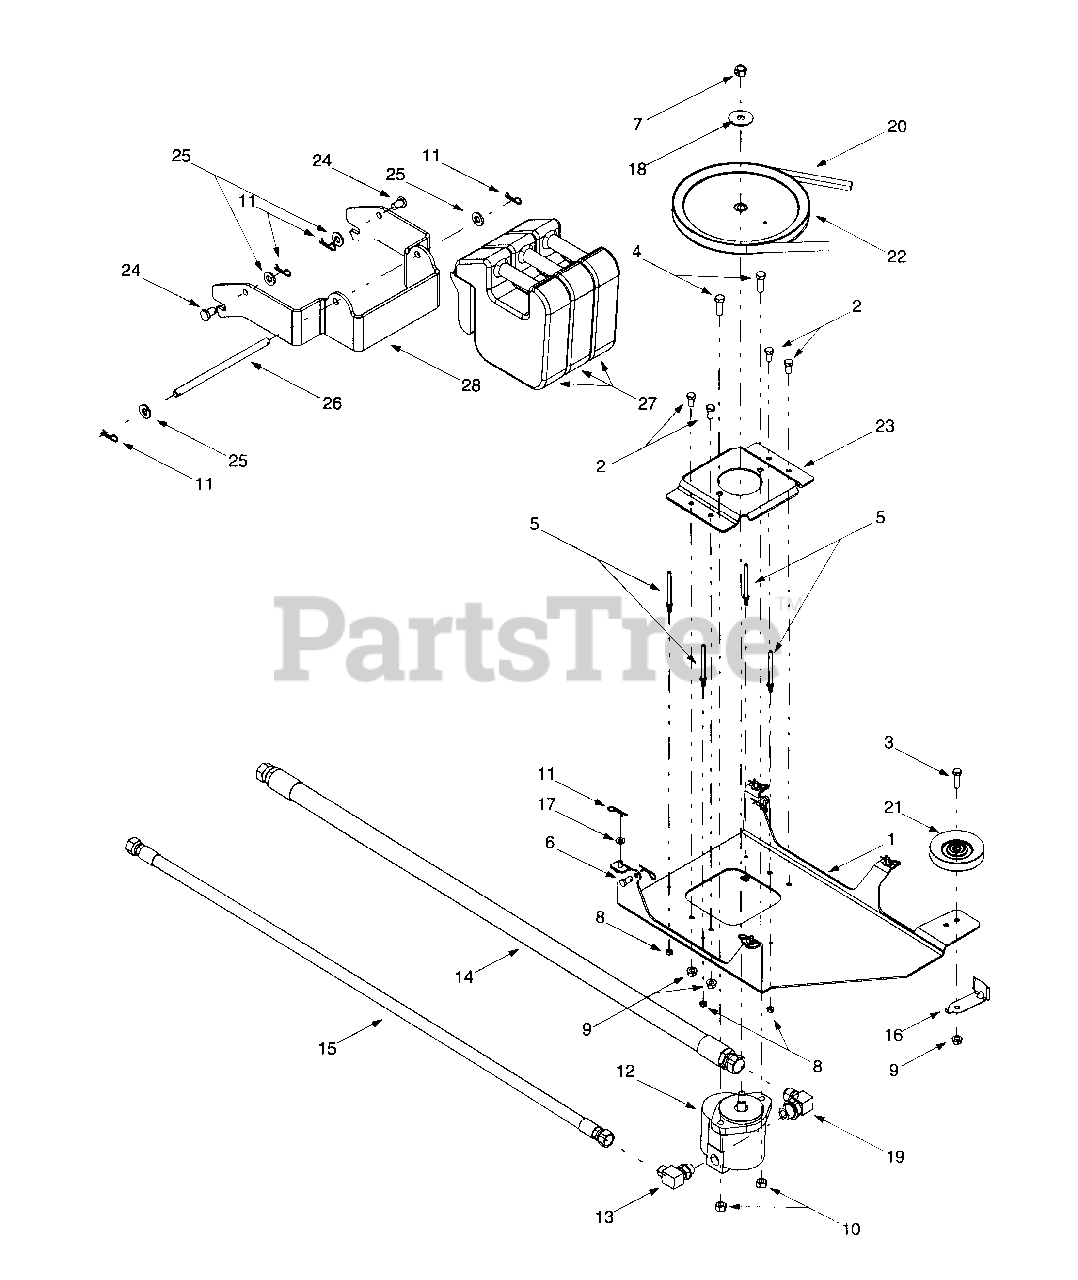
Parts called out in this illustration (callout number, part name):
1	Hydraulic Pump Bracket Ass'y
2	Hex Cap Screw, 3/8-16 x .75
3	Hex Cap Screw, 3/8-16 x 1.25
4	Hex Cap Screw, 7/16-20 x 1.25
5	Belt Keeper Pin
6	Clevis Pin, 3/8 x .75
7	Hex Lock Nut, 1/2-20
8	Hex Lock Nut, 1/4-20
9	Hex Lock Nut,3/8-16
10	Hex Lock Nut, 7/16-20
11	Click Pin, .092 x 1.64
12	Eaton Hydraulic Pump
13	90° Hydraulic Adapter, 7/8
14	Hydraulic Hose, 1.0625-12 x 54
15	Hydraulic Hose, .875-14 x 49
16	Belt Guard
17	Flat Washer, .344 x .688 x .065
18	Flat Washer, .531 x 1.75 x .090
19	90° Hydraulic Adapter, 1-1/16
20	V-belt
21	Idler Pulley, 5/8 x 4.0
22	Drive Pulley, 10.0
23	Pump Mounting Bracket
24	Clevis Pin, .5 x .78
25	Flat Washer, .531 x 1.062 x .134
26	Weight Guard Rod
27	45 lb. Suitcase Weight
